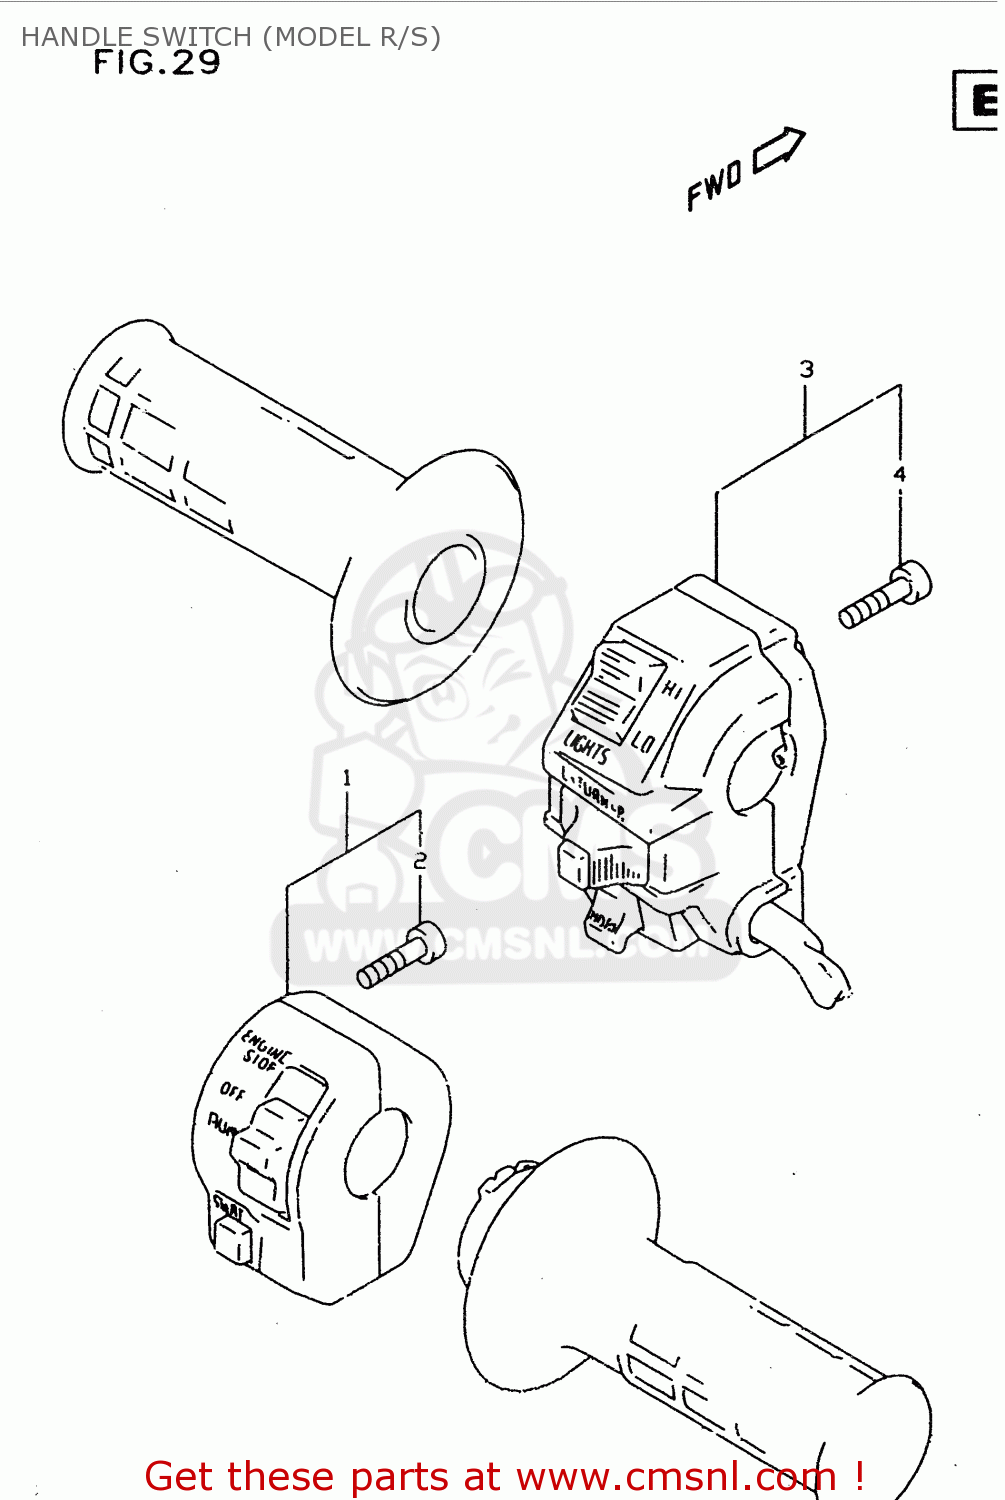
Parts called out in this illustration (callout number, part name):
1	SWITCH ASSY, HANDLE, RH
2	SCREW
3	SWITCH ASSEMBLY,HANDLE,LEFT
4	SCREW
